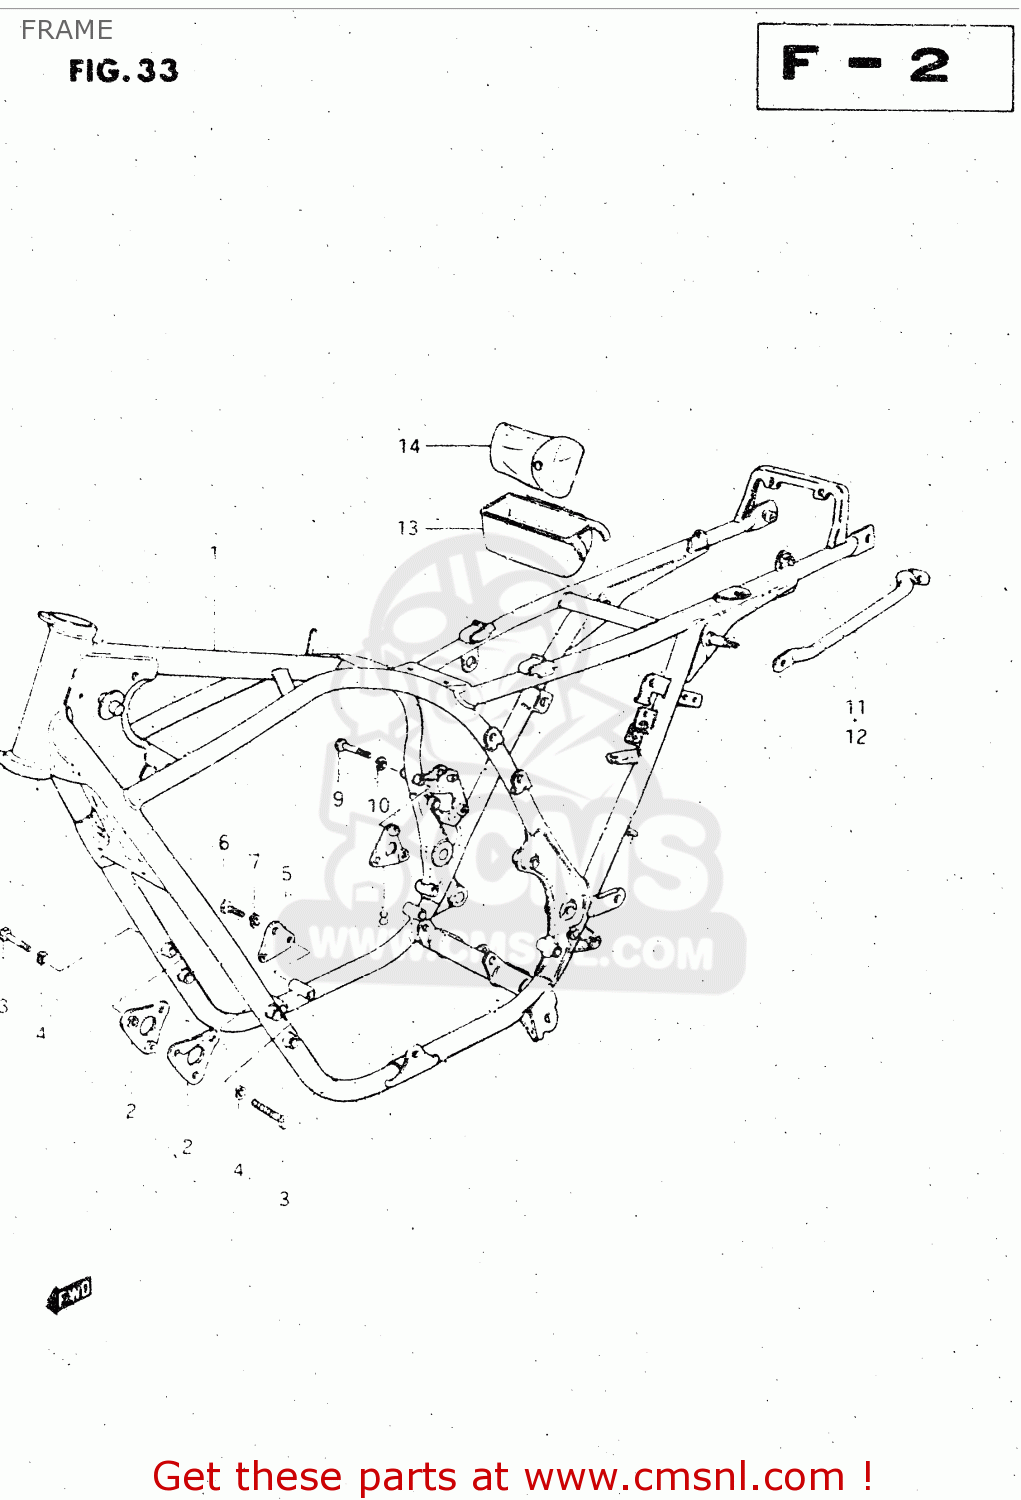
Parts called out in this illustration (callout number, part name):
1	FRAME
2	PLATE,ENGINE MOUNTING
3	BOLT
4	LOCK WASHER
5	PLATE,ENGINE MOUNTING
6	BOLT
7	LOCK WASHER
8	PLATE,ENGINE MOUNTING
9	BOLT 8X55
10	LOCK WASHER
11	GRIP,FRAME
12	GRIP, FRAME HANDLE LH
13	HOLDER,TOOL
14	TOOL SET
